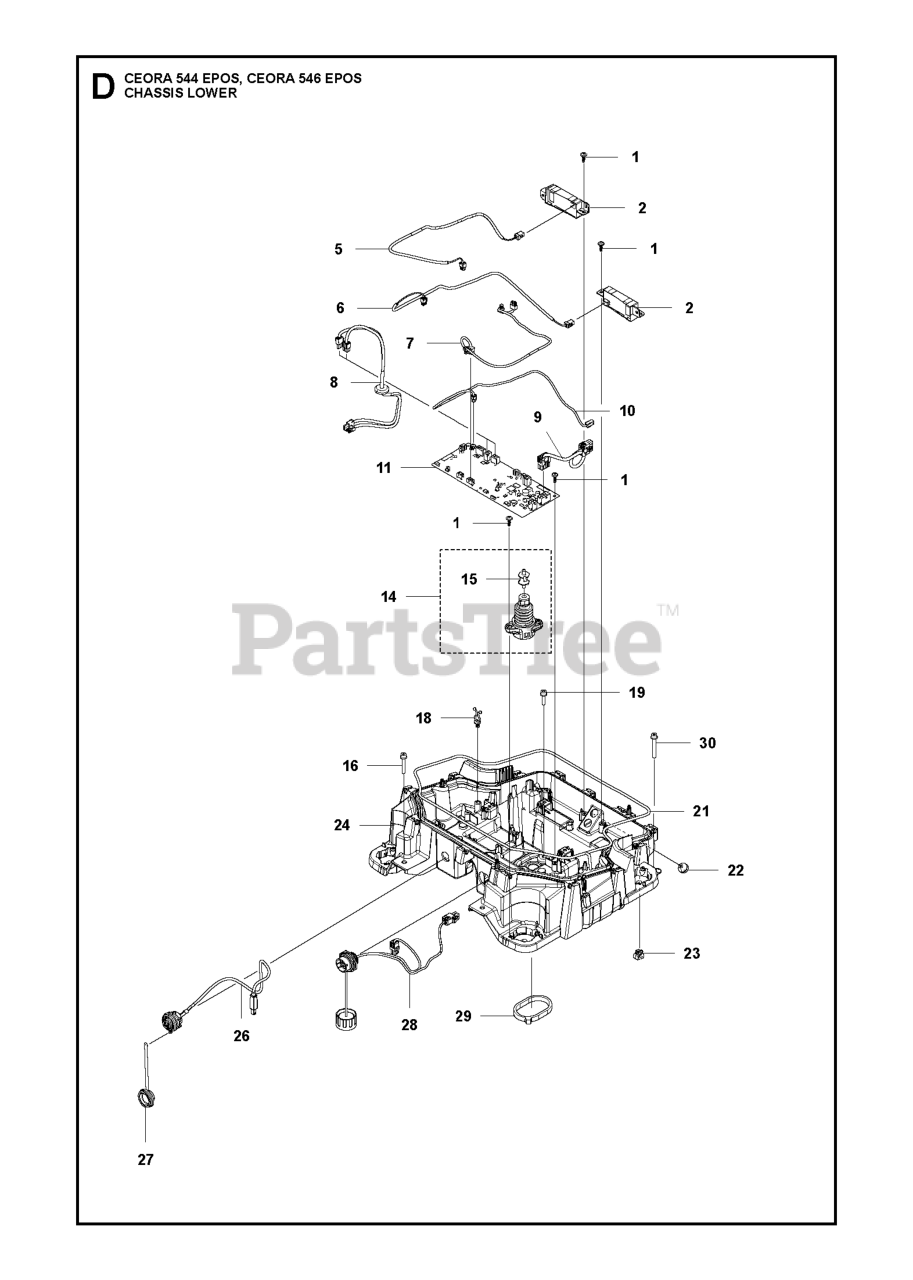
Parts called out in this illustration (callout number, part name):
1	SCREW ITXPANT
2	HOUSING ASSY HOUSING ASSY LOOP
5	WIRING ASSY MAGNETIC & LOOP SE
6	WIRING ASSY MAGNETIC & LOOP SE
7	WIRING ASSY APPLICATION BOARD
8	WIRING ASSY APPLICATIONBOARD -
9	WIRING ASSY CHASSI TO APP BOAR
10	WIRING ASSY EXTENSION LED LIG
11	PRINTED CIRCUIT ASSY PCBA APPL
14	JOYSTICK ASSY FOR RUBBER DAMPE
15	DAMPER RUBBER A19.5 H19 M6X11.
16	SCREW ISO 10644 M6X30-10.9-S1
18	HOLDER TWIST LOCK
19	SCREW
21	SEALING STRIP P 15 CHASSI LOW
22	GROMMET M16
23	INSERT SCREW BLOCK
24	CHASSIS LOWER - DRIVE UNIT
26	WIRING ASSY
27	CAP SEALING CAP FOR FRONT PANE
28	WIRING ASSY APPLICATION BOARD
29	SEALING CHASSIS LOWER - MOTOR
30	SCREW ISO 10644 M6X45-10.9-S1
